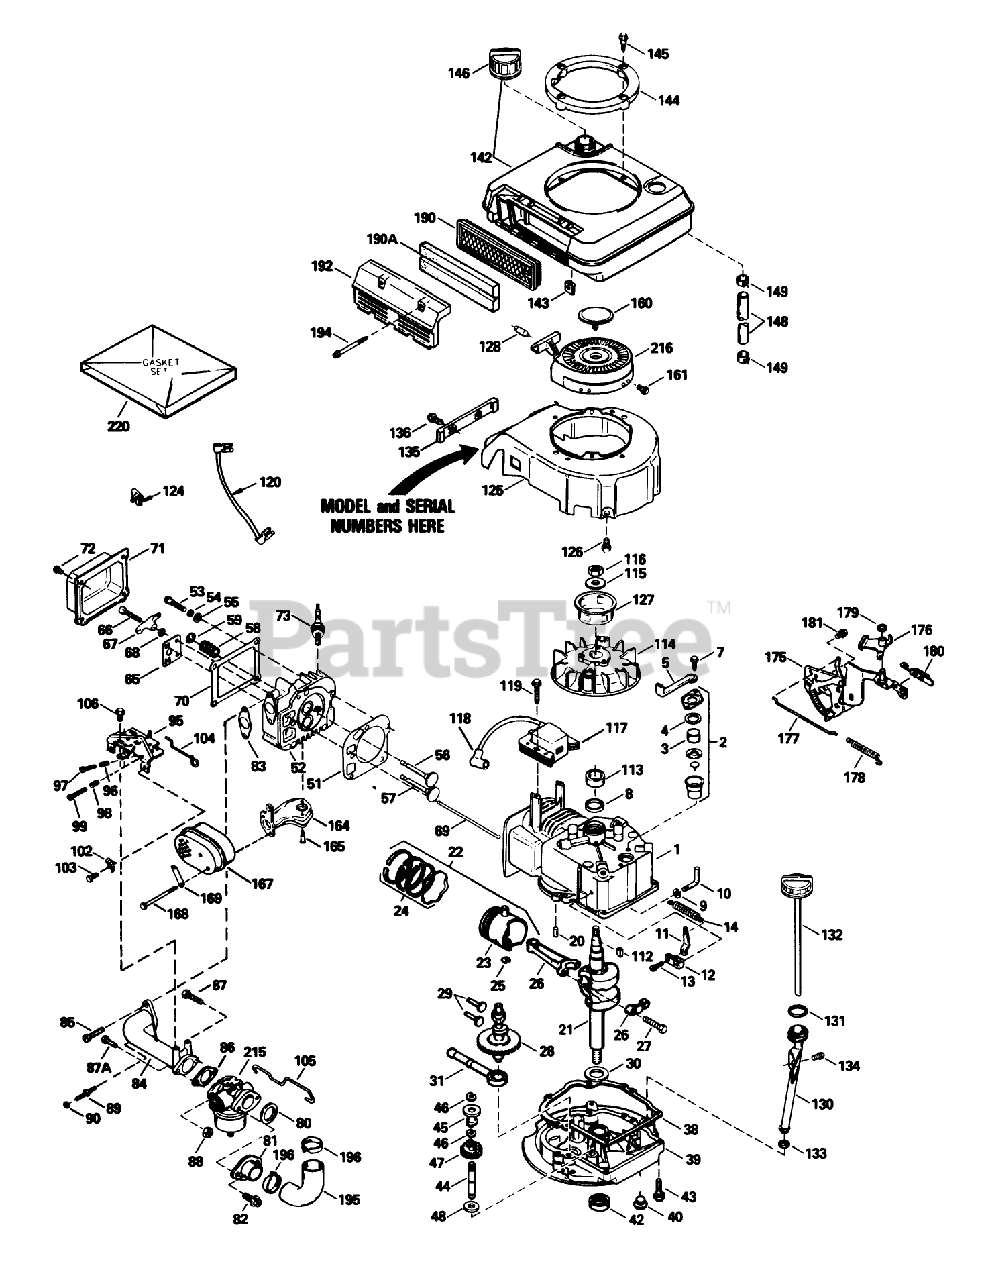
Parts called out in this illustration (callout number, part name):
1	Cylinder Assembly (Incl. Ref. #8 20)
2	Breather Assy. (Incl. Ref. #46 thru 51)
3	Element-Breather
4	Gasket-Breather
5	Tube-Breather
7	Screw (10-24 x 9/16)
8	Seal-Oil
9	Washer-Flat
10	Rod, Governor (Incl. No. 36)
11	Governor Lever
12	Clamp-Lever, Governor
13	Screw
14	Spring-Extension
20	Pin-Dowel
21	Crankshaft
22	Piston-Pin Ring Assy. (Std.)(Incl. Ref. #14A, 15 16)
23	Piston Pin Assy. (Std)(Incl. Ref. #16)
24	Piston Ring Set Std.
25	Ring-Retaining, Piston Pin
26	Rod Assy., Connecting (Incl. Ref. #17)
27	Bolt-Rod, Connecting
28	Camshaft
29	Valve Lifter
30	Washer-Thrust
31	Oil Pump ASM
38	Gasket
39	Flange-Mounting (Incl. Ref. #26, 27 39)
40	Plug Oil Drain
42	Seal-Oil
43	Screw (1/4-20 x 1-1/4)
44	Shaft-Governor
45	Spool-Governor
46	Ring-Retaining
47	Governor Gear ASM
48	Washer
51	Gasket-Cylinder Head
52	Head-Cylinder
53	Screw (5/16-18 x 1-1/2)
54	Washer-Flat
55	Washer-Belleville
56	Valve-Intake Std. (Incl. Ref. #59)
57	Valve-Exhaust Std. (Incl. Ref. #59)
58	Spring-Valve
59	Cap-Valve, Spring
65	Guide-Push Rod
66	Stud-Arm, Rocker
67	Arm-Rocker
68	Nut (1/4-28)
69	Rod-Push
70	Gasket-Cover, Rocker Arm
71	Cover-Rocker Arm
72	Screw
73	Spark Plug-Resistor (R N 4C)
80	Gasket-Air Cleaner
81	Adapter-Air Cleaner
82	Screw-Round Hd.
83	Gasket-Intake Pipe
84	Pipe-Intake
85	Screw-Hex. Hd.
86	Gasket
87A	Screw-Special Hex. Hd.
88	Nut and Lock Washer (1/4-28)
89	Stud-Manifold
90	Nut and Lock Washer (1/4-28)
95	51089 SUPP TO MANUA
96	61709/GIL1515A/95-5
97	Screw
98	Spring-Compression
99	Screw
102	Conduit
103	Screw (10-32 x 3/8)
104	2035A67 ADD.ASSEMBL
105	Link-Throttle
106	Screw (10-24 x 9/16)
112	Key-Flywheel
113	Spacer
114	Flywheel
115	Washer-Belleville
116	Nut-Flywheel
117	Solid State
118	Cover-Spark Plug
119	Screw
120	Ground Wire
124	Clip-Wire
125	Housing-Blower
126	Screw (1/4-20 x 1/2)
127	Hub-Starter
128	Retainer-Starter Rope
130	Tube-Oil Fill
131	O-Ring
132	Dipstick-Oil Fill
133	Gasket
134	Screw (10-32 x 1/2)
135	Cover-Blower Housing
136	Screw (10-32 x 1/2)
142	Shroud Tank Assembly (Incl. Ref. #143 146)
143	Clip-U-Nut
144	Ring-Shroud
145	Screw
146	Cap-Fuel
148	Line-Fuel
149	Clamp-Line, Fuel
160	Plug Starter
161	Screw, Hex Hd.
164	Exhaust Manifold Assembly
165	Screw-Torx Hd. Shoulder
167	Muffler Assembly
168	Screw (5/16-18 X 2-1/2)
169	62513 SNWTHWR W/284
175	Bracket-Brake
176	Lever-Brake
177	Link-Control
178	Spring-Extension
179	Ring-Retaining
180	Terminal
181	Screw (1/4-20 x 3/8)
190	Filter-Air Cleaner
190A	Filter-Pre-Cleaner
192	Cover-Air Cleaner
194	Screw-Filester Hd.
195	Tube-Air Cleaner
196	Clamp-Air Cleaner
215	Carburetor Assembly (Incl. Ref. #86)
216	Starter-Rewind
220	Gasket Set
